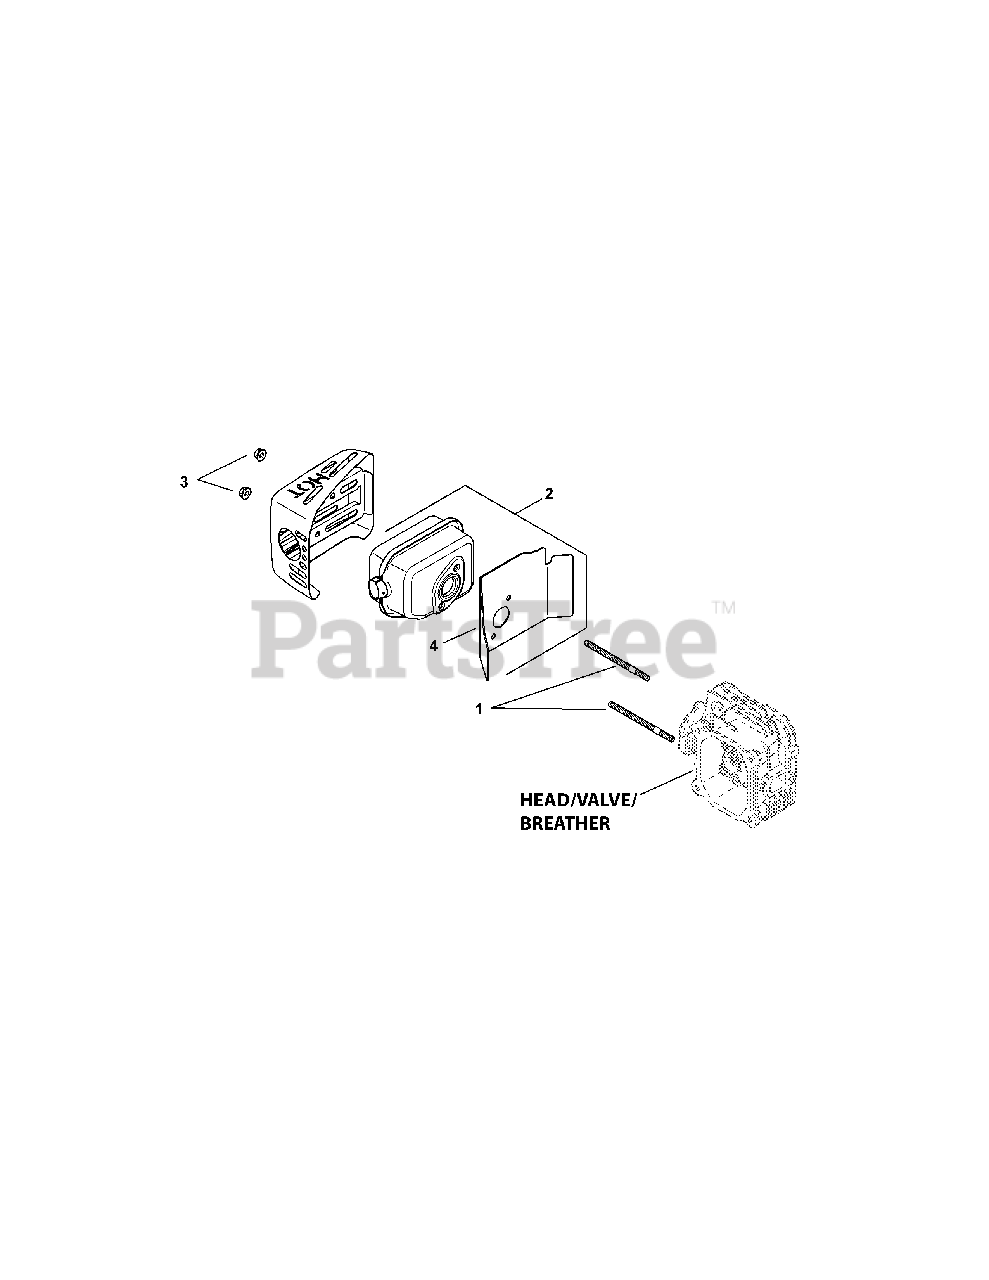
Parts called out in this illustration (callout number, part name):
1	Stud Kit, M6
3	Nut, Hex Flange Lock, M6
4	Muffler Gasket
